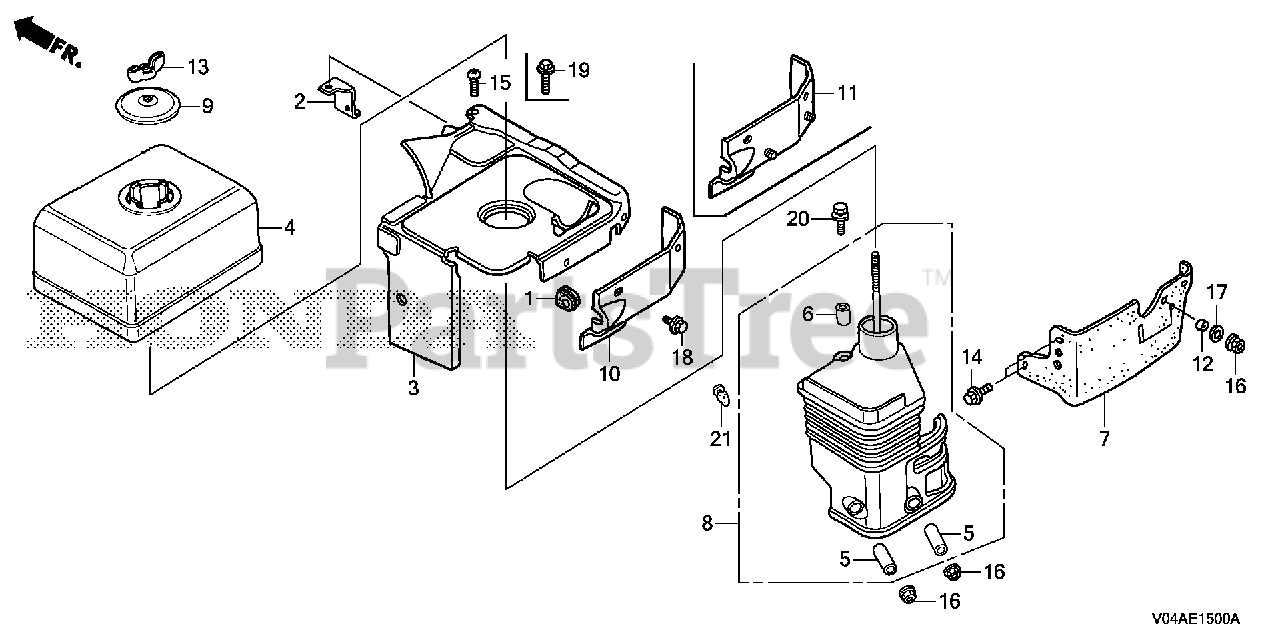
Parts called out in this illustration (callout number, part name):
1	GROMMET, OIL PIPE HOLDER
2	STAY, ENGINE CONTROL COVER
3	COVER, CONTROL
4	COVER, AIR CLEANER (SEMI-DRY)
5	COLLAR, AIR CLEANER
6	COLLAR B, AIR CLEANER
8	ELBOW, AIR CLEANER
9	CAP, AIR CLEANER
10	COVER, AIR IN.
13	NUT, TOOL BOX SETTING
15	SCREW, PAN (6X8) (SOURCE: VINTAGE PARTS INC.)
16	NUT, FLANGE (6MM)
18	BOLT, FLANGE (6X8)
20	BOLT, FLANGE (6X20)
21	PLUG, CONE TYPE
